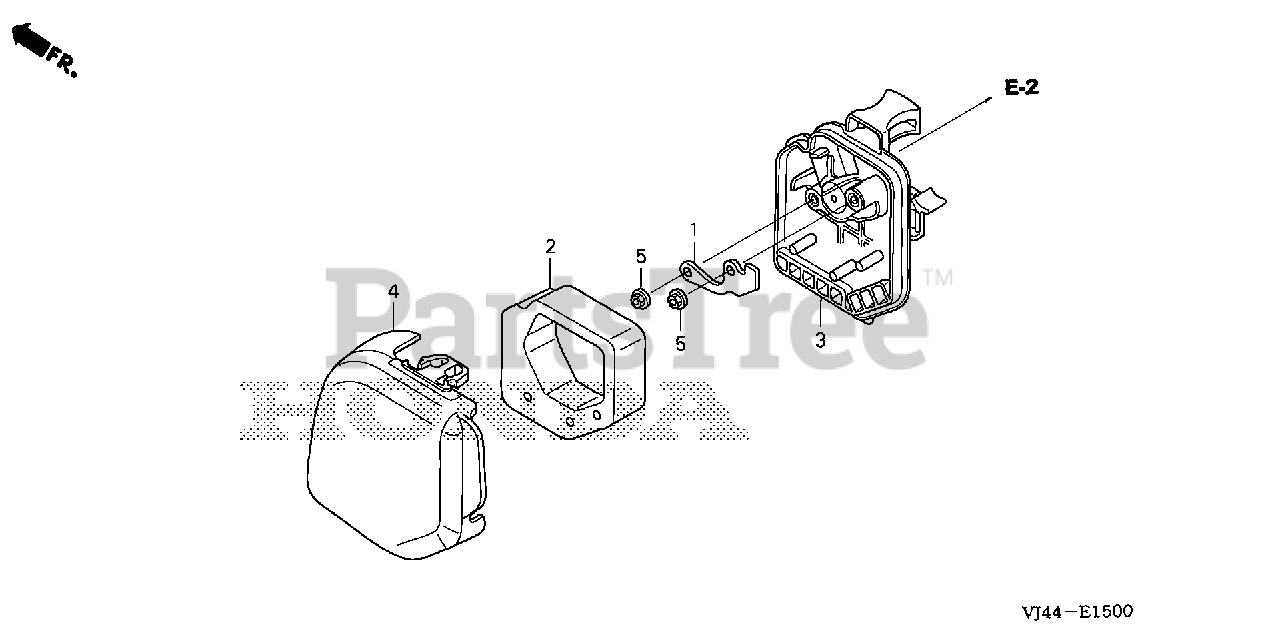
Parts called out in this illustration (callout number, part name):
1	PLATE, OIL TRAP
2	ELEMENT, AIR CLEANER
3	HOUSING, AIR CLEANER
4	COVER, AIR CLEANER
5	NUT, FLANGE (5MM)
